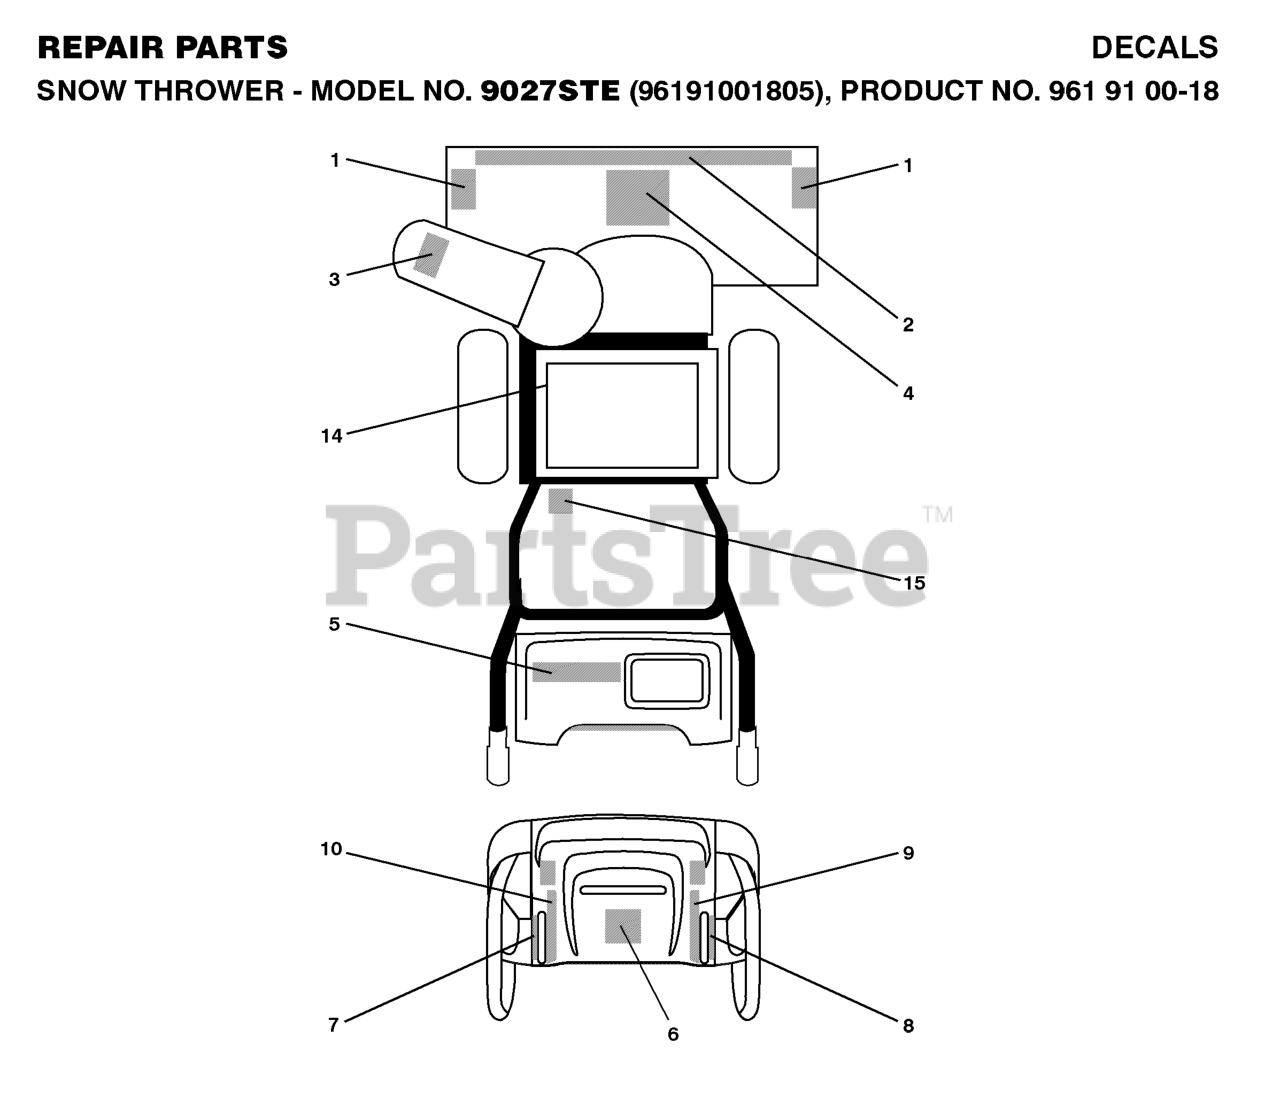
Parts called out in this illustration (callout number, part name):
1	DECAL.AUGER.SAFETY.
3	DECAL.CHUTE.SAFETY.
4	DECAL.AUGER."
6	DECAL.CONSOLE.INSTRUCTION
7	DECAL.POWER.STEER.LT.TRIG.INT
8	DECAL.POWER.STEER.RT.TRIG.INT
10	DECAL.REM.DEFLECTOR.LT
14	DECAL.BELT.GUARD.
15	DECAL.FENDER
